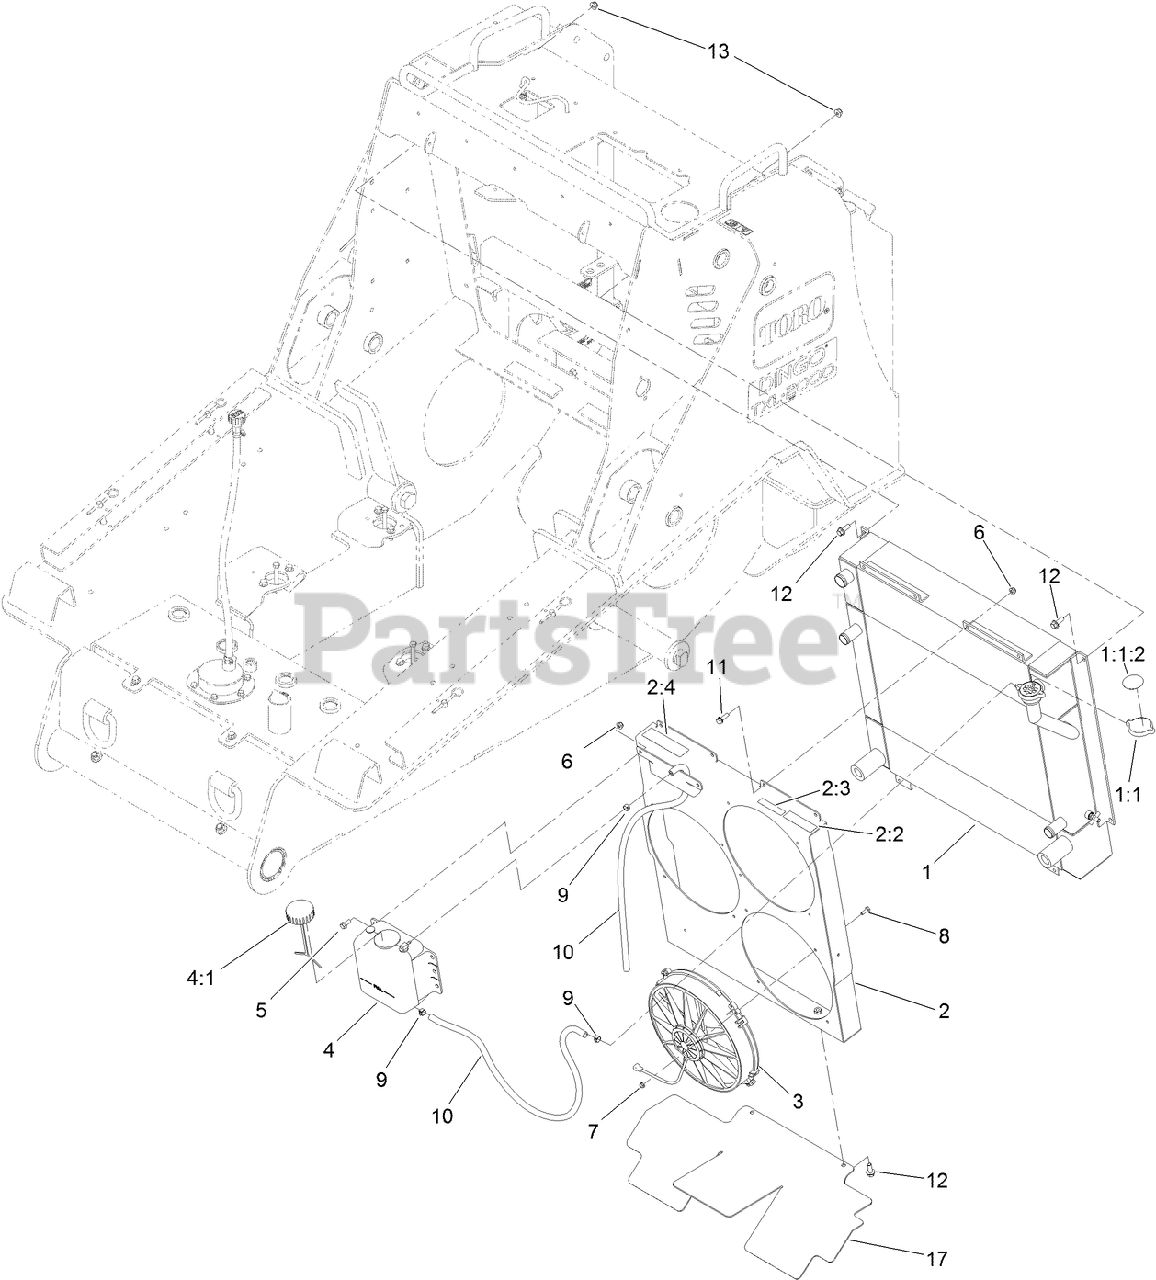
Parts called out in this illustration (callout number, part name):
1	RADIATOR/COOLER ASM
1:1	RADIATOR CAP ASM
1:1:2	DECAL-DANGER
2	COOLER SHROUD ASM
2:2	DECAL-RADIATOR FILL
2:3	DECAL-WARNING, FAN
2:4	DECAL-DANGER
4	COOLANT RESERVOIR ASM
4:1	CAP-RESERVOIR
5	SCREW-HHF
6	NUT-HF, NI
7	NUT-HF
8	SCREW-HH
9	CLAMP-HOSE
10	HOSE-FUEL
11	SCREW-HHF
12	SCREW-HHF
13	NUT-HF, NI
17	BAFFLE-RUBBER
